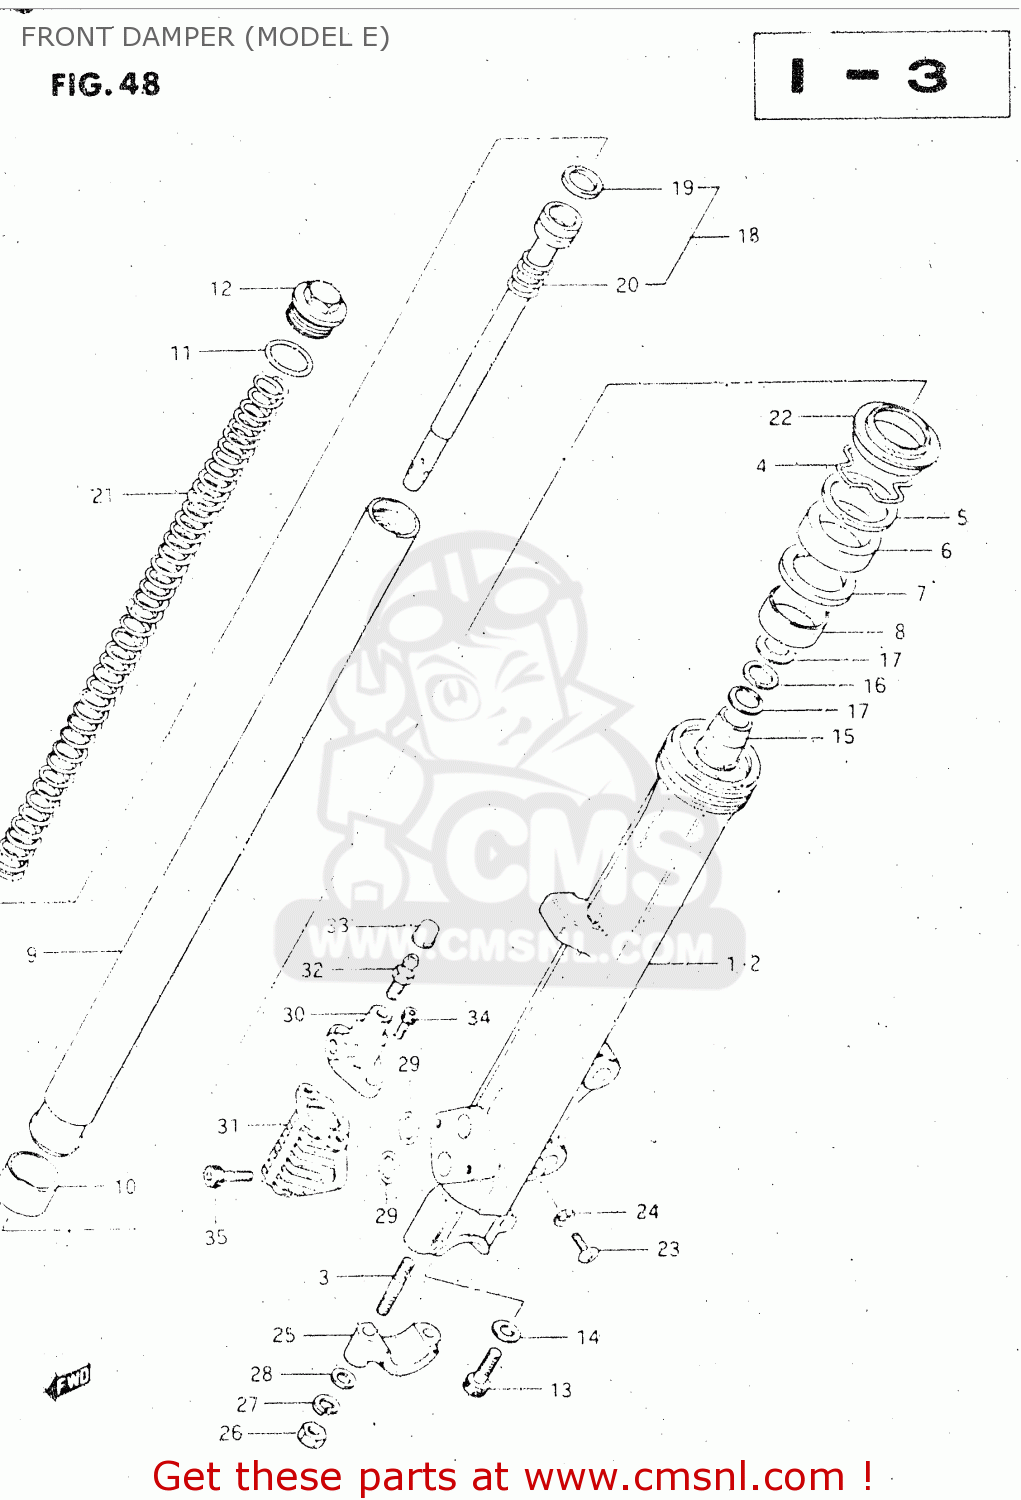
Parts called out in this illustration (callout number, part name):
1	TUBE,OUTER,RIGHT
2	TUBE,OUTER,LEFT
3	STUD 8X30
4	RING,STOPPER
5	WASHER. FRONT FORK
6	OIL SEAL,FRONT FORK
7	WASHER
8	METAL,SLIDE
9	TUBE,INNER
10	METAL,FRONT FORK PISTON
11	O RING
12	CAP
13	BOLT,FORK CYLINDER(10X25)
14	GASKET (NAS)
15	PIECE,OIL LOCK
16	WASHER
17	SPRING,LEAF
18	CYLINDER,FRONT FORK
19	RING,PISTON
20	SPRING,REBOUND
21	SPRING
22	SEAL,DUST
23	SCREW
24	GASKET,DRAIN,PLUG (NAS)
25	HOLDER,AXLE
26	NUT
27	WASHER,LOCK,8.
28	WASHER
29	O RING
30	PLUNGER SET
31	PDF ASSEMBLY
32	BREATHER,AIR
33	CAP,BREADER
34	BOLT
35	BOLT
